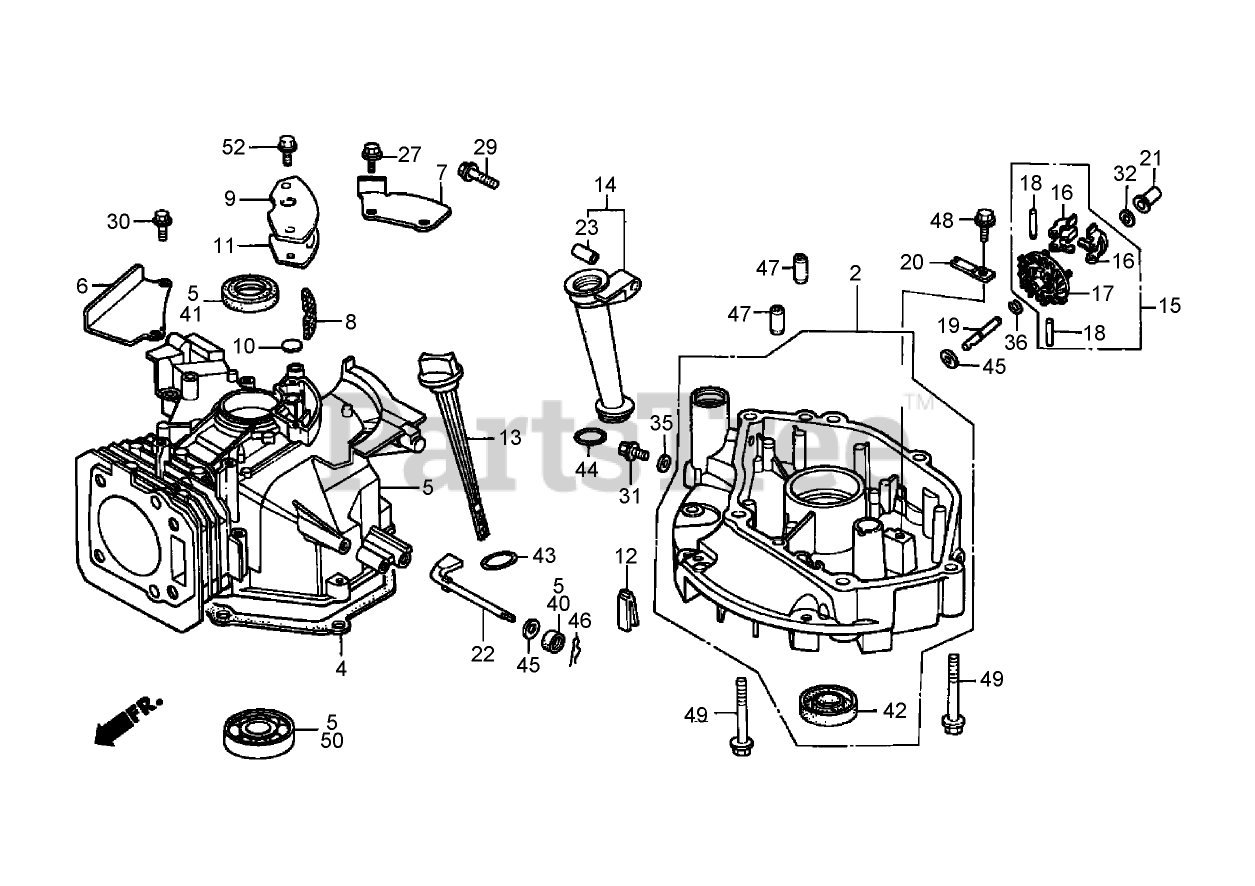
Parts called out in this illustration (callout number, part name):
2	OIL PAN ASM
4	GASKET-PAN, OIL
5	CYLINDER ASM
6	Plate-Guide
7	Plate A-Guide
8	Filter-Breather
9	Cover-Breather
10	VALVE-BREATHER
11	GASKET-COVER, BREATHER
12	RUBBER-RETURN, OIL
13	Dipstick-Oil
14	EXTENSION-FILLER, OIL (106 mm)
15	GOVERNOR ASM
16	Weight-Governor
17	HOLDER-WEIGHT, GOVERNOR
18	PIN-WEIGHT, GOVERNOR
19	SHAFT-HOLDER, GOVERNOR
20	Plate-HOLDER, Governor Shaft
21	SLIDER-GOVERNOR
22	SHAFT-ARM, GOVERNOR
23	Collar-Extension
27	BOLT-FLANGE (6X12) (C T200)
29	Bolt-Flange (6X32)
30	BOLT-FLANGE (6X20) (C T200) (engine serial numbers up to 6702082)
31	Bolt-PLUG, Drain
32	WASHER-THRUST (6MM)
35	WASHER-PLUG, DRAIN (102MM)
36	CLIP-HOLDER, GOVERNOR
40	SEAL-OIL (6X11X4)
41	SEAL-OIL (25X38X7)
41	SEAL-OIL (25X38X7) (ARAI)
42	SEAL-OIL (25.4X40X7)
43	O-Ring (22.5X2.2)
44	O-Ring (26X2.7)
45	WASHER-PLAIN (6MM)
46	PIN-LOCK (8MM)
47	Pin-Dowel (8X14)
48	Bolt-Flange (6X12)
49	BOLT-FLANGE (8X50)
50	BEARING-BALL, RADIAL (6205)
52	BOLT-FLANGE (6X14) (C T200)
